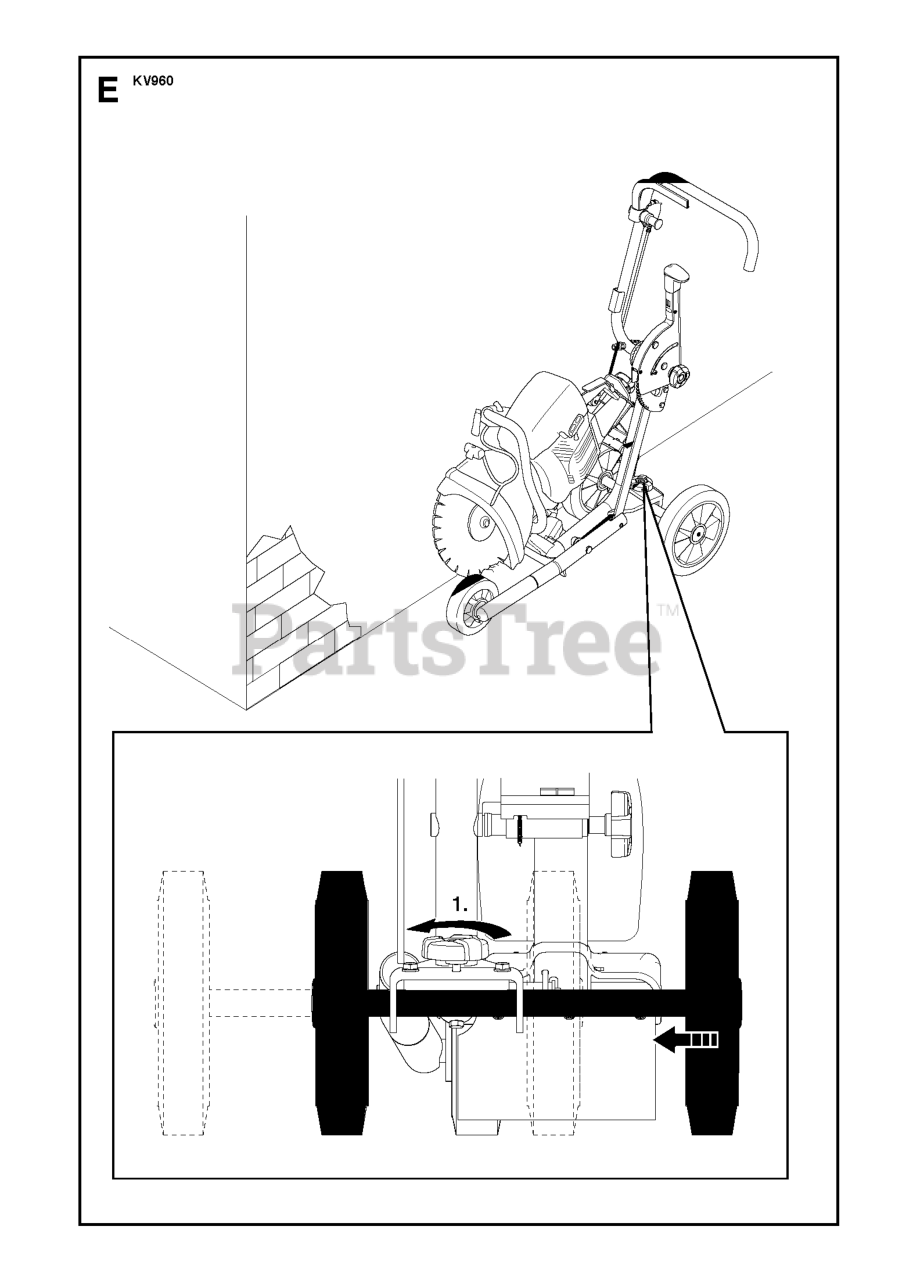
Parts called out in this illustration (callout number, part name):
1	CYLINDER
2	PISTON CPL 48 MM
3	CYLINDER PLUG
4	SUPPORT BUSHING
5	DECOMPRESSION VALVE
6	SCREW MC6S 5X25
7	SPARK PLUG RCJ7Y
9	PISTON RING
10	WRIST PIN CLIP
13	GASKET SET
